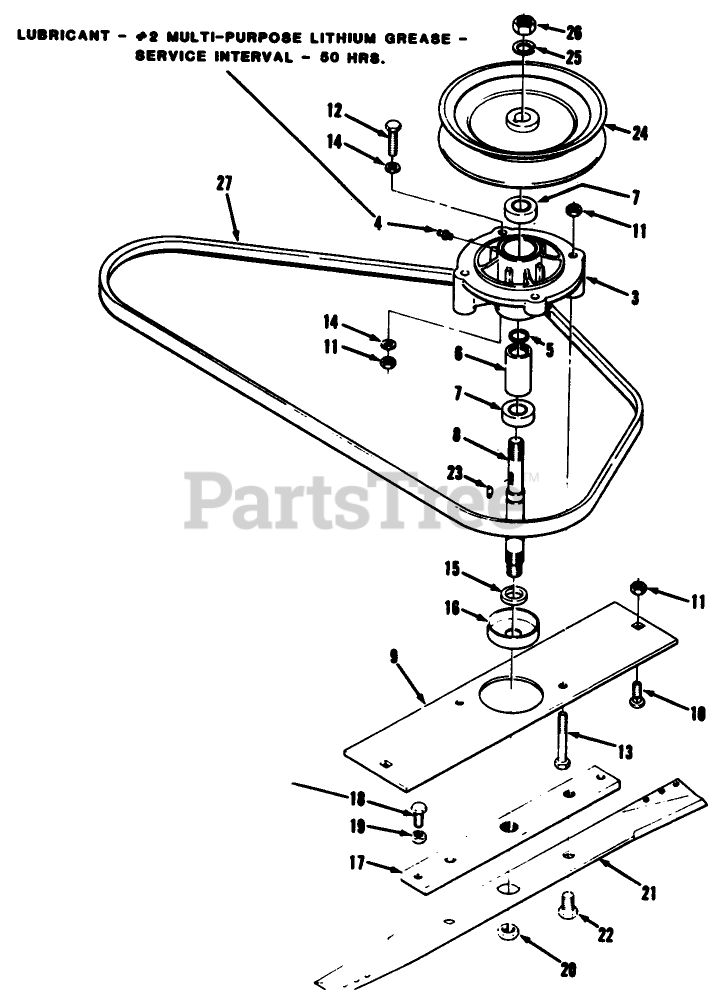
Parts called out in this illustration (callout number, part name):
3	HOUSING-SPINDLE
4	Fitting-Grease
5	SNAP RING
7	BALL BEARING
8	SHAFT
9	BAR R
10	Bolt
11	NUT
12	Bolt
13	Bolt
14	Washer
15	SPACER-BLADE
16	CUP-SPINDLE
17	BAR-BLADE R
18	Bolt
19	NUT-HEX, JAM
20	Nut
21	Blade
22	HEX BOLT 1/2-13X3/4
23	KEY-HI-PRO
24	PULLEY
25	Lockwasher
26	Nut
27	V-BELT DRIVE
